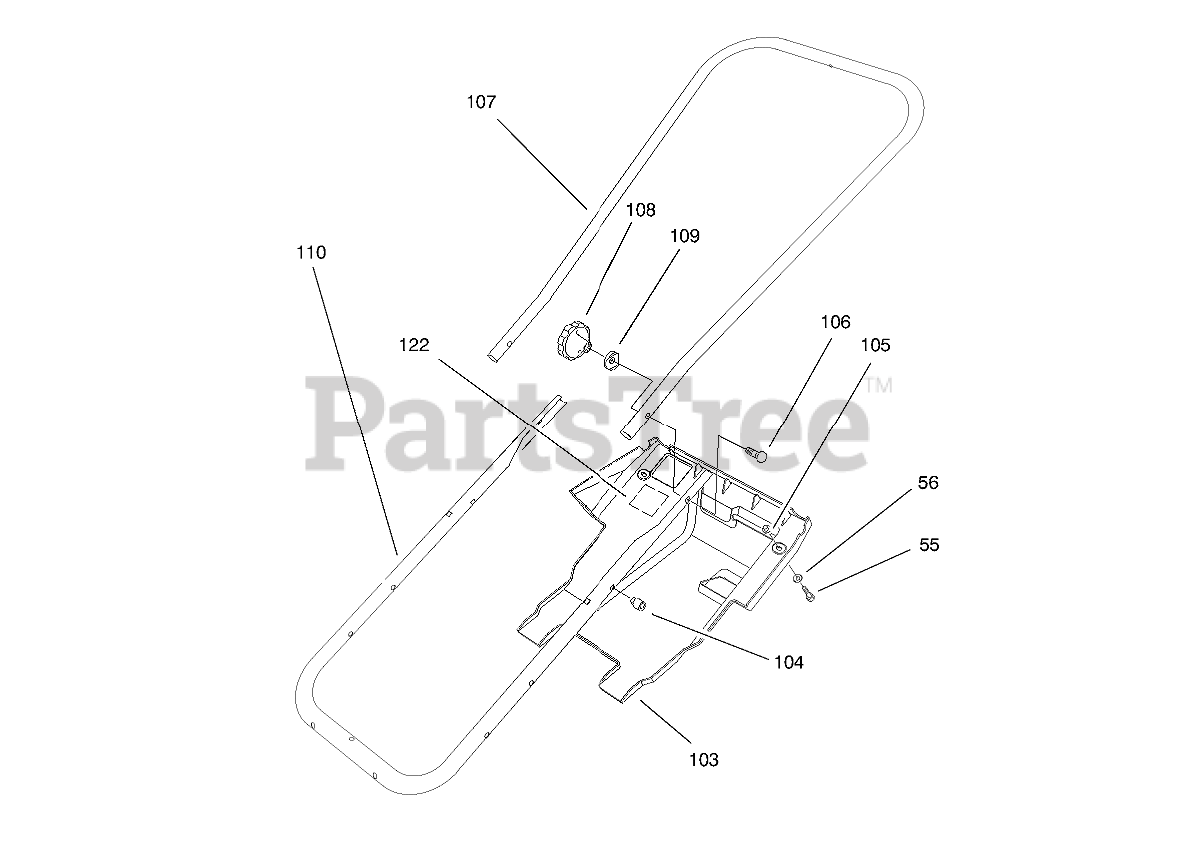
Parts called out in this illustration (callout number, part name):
55	SCREW-HWHTF
56	WASHER-FLAT
103	SHROUD
104	NUT-EXPANSION
105	NUT-CLIP
106	SCREW-HANDLE
107	Handle-Upper
109	WASHER-CURVED
110	Tube-Frame
122	DECAL
